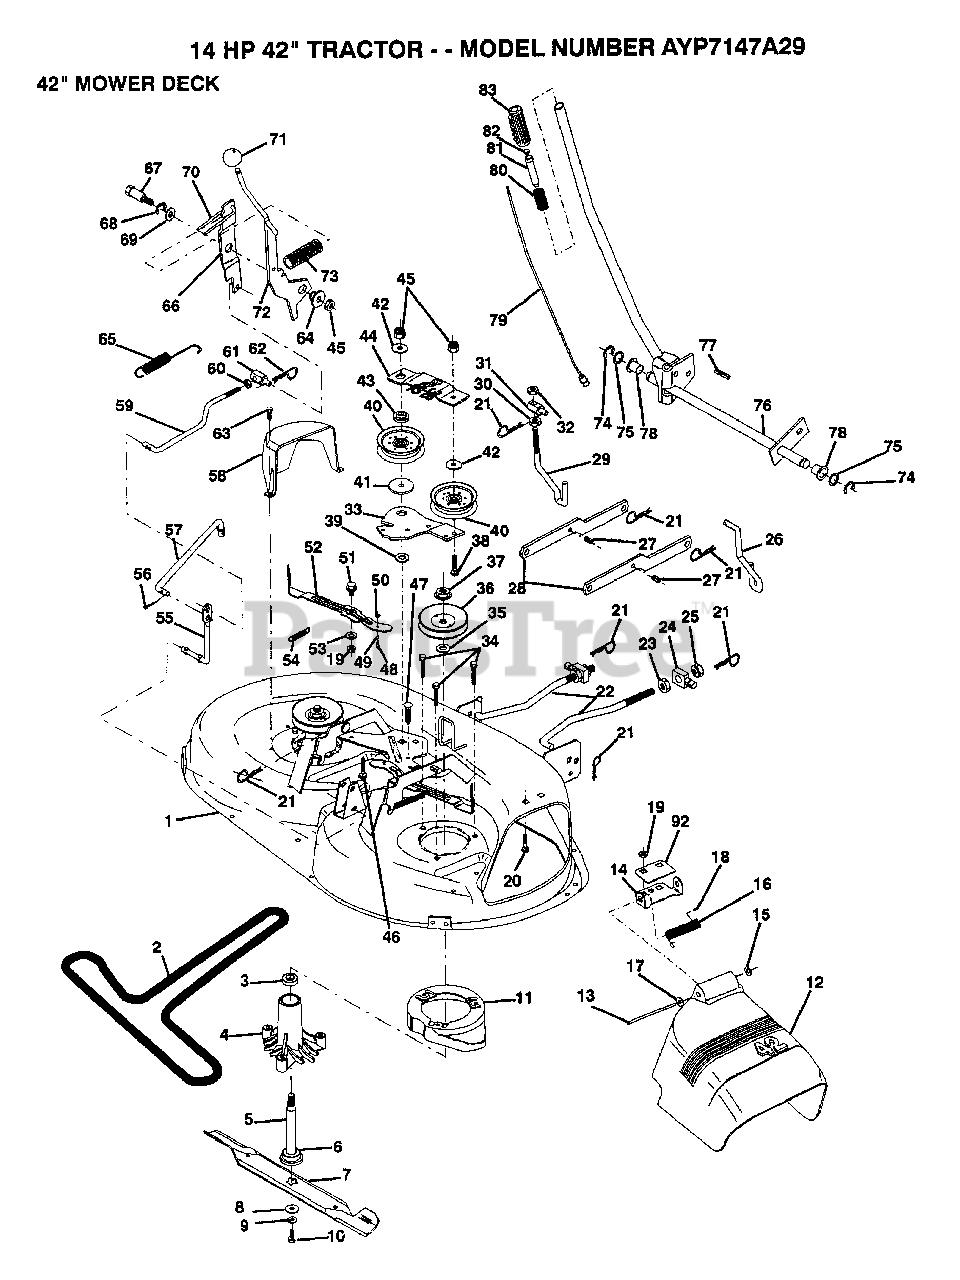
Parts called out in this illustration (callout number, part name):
2	BELT-V.92.4.MWR
3	BEARING
4	HSG ASM MANDREL
6	BEARING.BALL
8	WASHER BLADE
10	BLADE BOLT
12	DEFLECTOR.SHIELD
13	HINGE ROD
14	DEFLECTOR BRKT
15	NUT PUSH M
16	SPRING TORSION
17	WASHER
18	CAP-SLEEVE LT
20	BOLT
22	LINK.FRONT
23	NUT
24	TRUNION
25	NUT.LK.W/WSH.1/2.
26	LINK LIFT RH
27	SPRING PIN
29	LIFT LINK LH
30	NUT
33	IDLER ARM
35	WASHER
38	BOLT
39	HARDENED WASHER
40	FLAT IDLER PULLEY
41	SPACER RETAINER
42	WASHER GT
43	RETAINER SPACER
44	IDLER ARM STIFF
46	BOLT CARRIAGE
47	XMAS TREE FASTNER
48	SHOULDER BOLT
50	LOCKNUT
52	BRAKE PAD ARM ASM
53	HARD SMALL WASHER
54	SPRING EXTENSION
55	PIVOT ROD
57	CLUTCH ROD SECOND
60	NUT
61	TRUNION
62	RETAINER M
63	SCREW LT
64	BUSHING
65	RETURN SPRING
66	CLUTCH ARM SECOND
67	SHOULDER BOLT
68	RING
69	WASHER
70	SPRING KEEPER
75	WASHER
76	LIFT SHAFT ASM
77	PIN-GROOVE LT
78	NYLON BEARING
83	GRIP
92	STIFFENER BRKT
